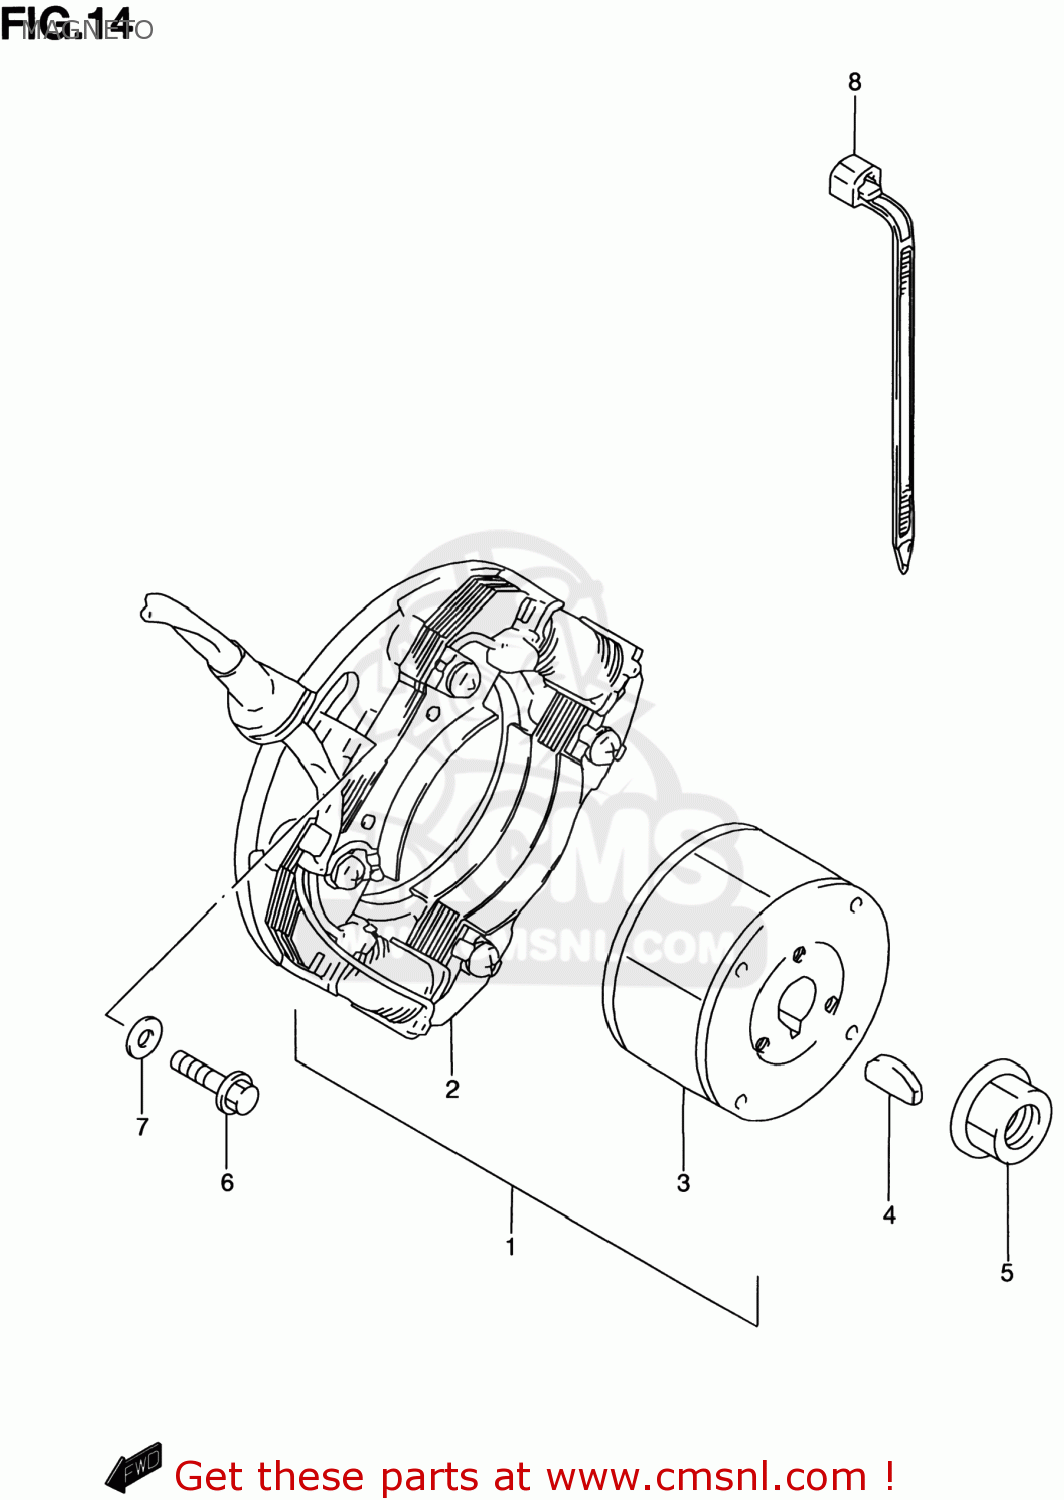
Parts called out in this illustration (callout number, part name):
1	MAGNETO ASSEMBLY
2	STATOR
3	ROTOR
4	KEY
5	NUT
6	SCREW
7	WASHER
8	CLAMP(L:125)
